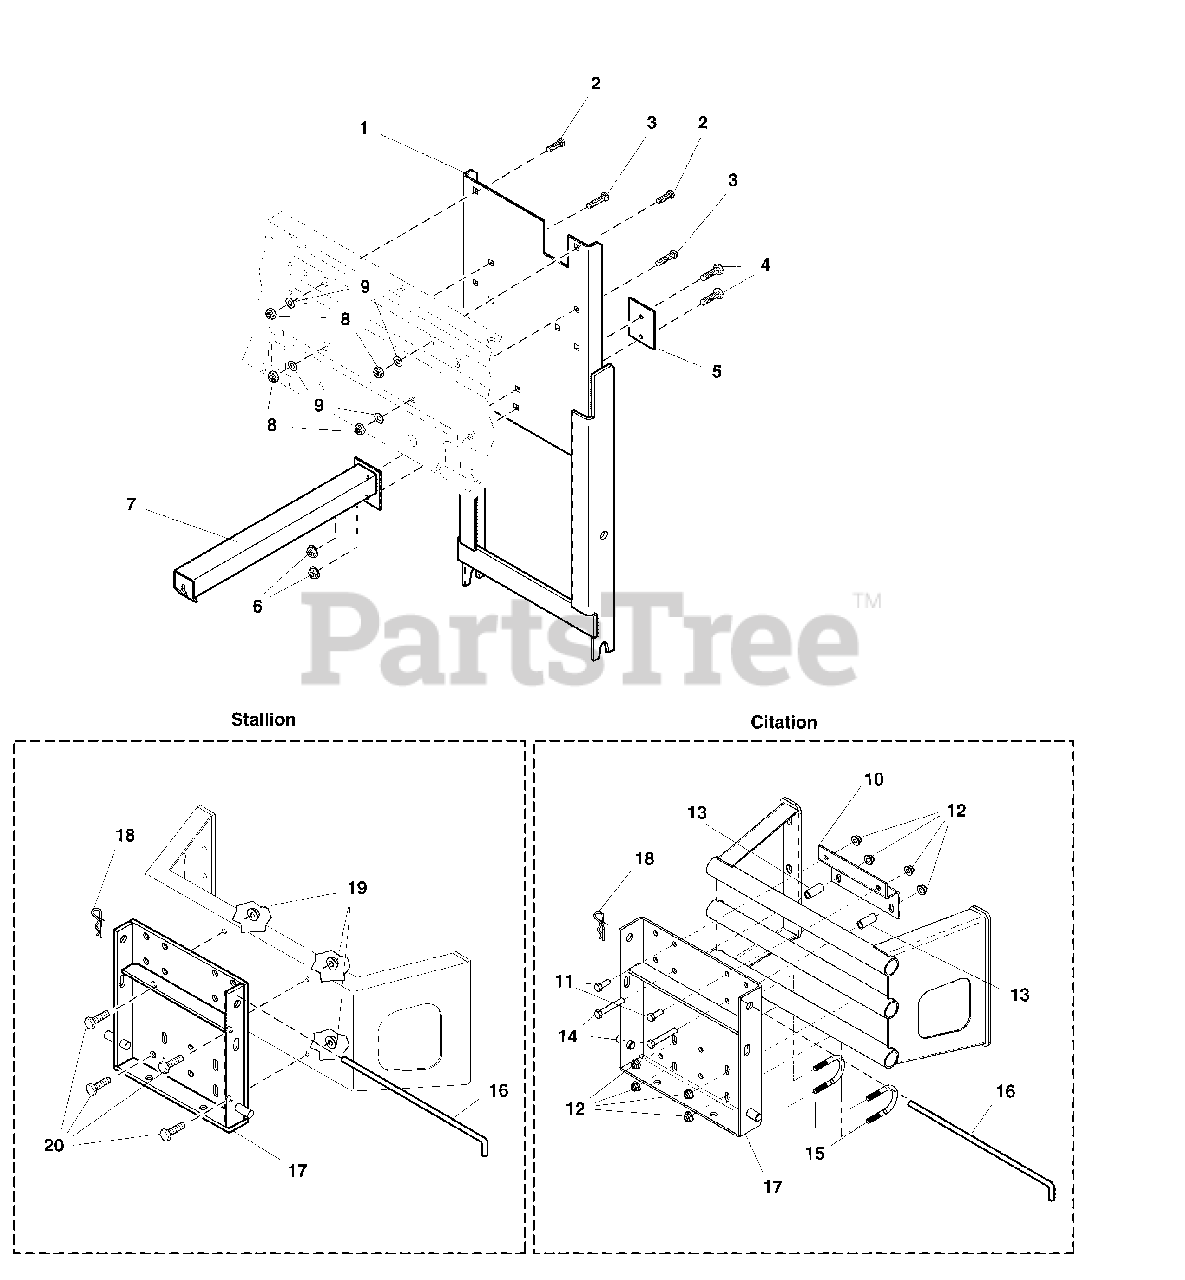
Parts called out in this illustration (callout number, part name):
1	SUPPORT ASSEMBLY
2	CARRIAGE BOLT, 5/16-18 x 3/4
3	CARRIAGE BOLT, 5/16-18 x 1-1/4
4	BOLT, 5/16-18 x 3/4
5	REINFORCEMENT PLATE
6	NUT, 5/16-18 Hex Small Serrated Flange
7	COVER LATCH ARM
8	NUT, 5/16-18 Hex Nylon Lock
9	WASHER, 5/16" SAE
10	ADAPTER PLATE
11	BOLT, 3/8-16 x 1
12	NUT, 3/8-16 HEX NYLOCK FLANGE
14	BOLT, 3/8-16 x 2-1/2
15	U-BOLT, 3/8 X 1-1/4
17	HITCH PLATE
18	HAIR PIN CLIP
19	NUT, 3/8-16 HEX NYLOCK FLANGE
20	BOLT, 3/8-16 x 1
